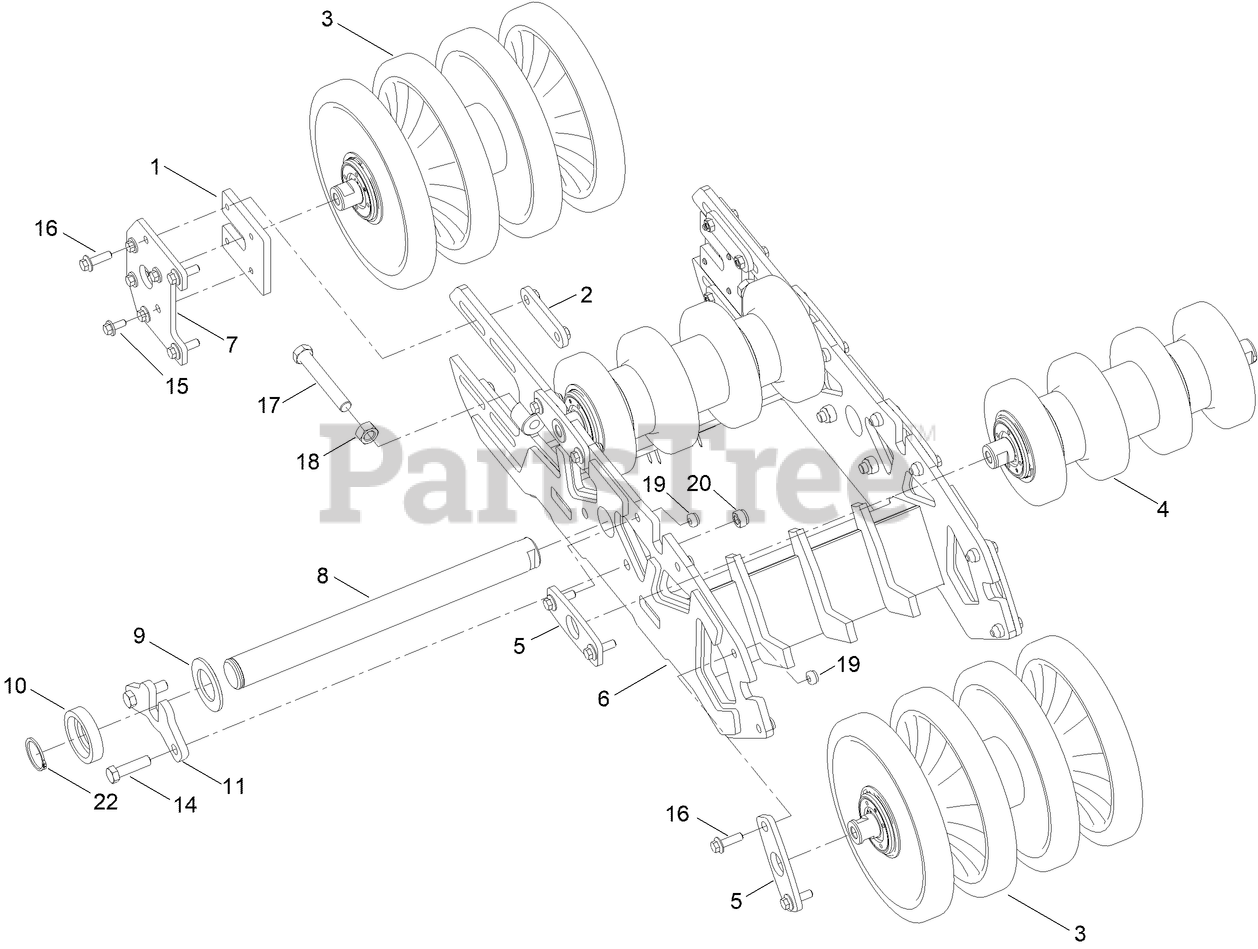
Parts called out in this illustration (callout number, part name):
1	TENSIONER-INNER, 19.5 IN TRACK
2	TENSIONER-CLAMPING, 19.5 IN TRACK
3	13.50" WHEEL ASM
4	8" WHEEL ASM
5	RETAINING PLATE
6	TRACK FRAME ASM
7	TENSIONNER OUTER PLATE
8	PIVOT-AXLE
9	PIVOT AXLE SPACER
10	SPACER
11	PIVOT AXLE PLATE
14	SCREW-HH
15	SCREW-HHF
16	SCREW-HHF
17	SCREW-HH,
18	NUT-HEX
19	NUT-HEX, LOCK
22	RING-RETAINING, EXTERNAL
